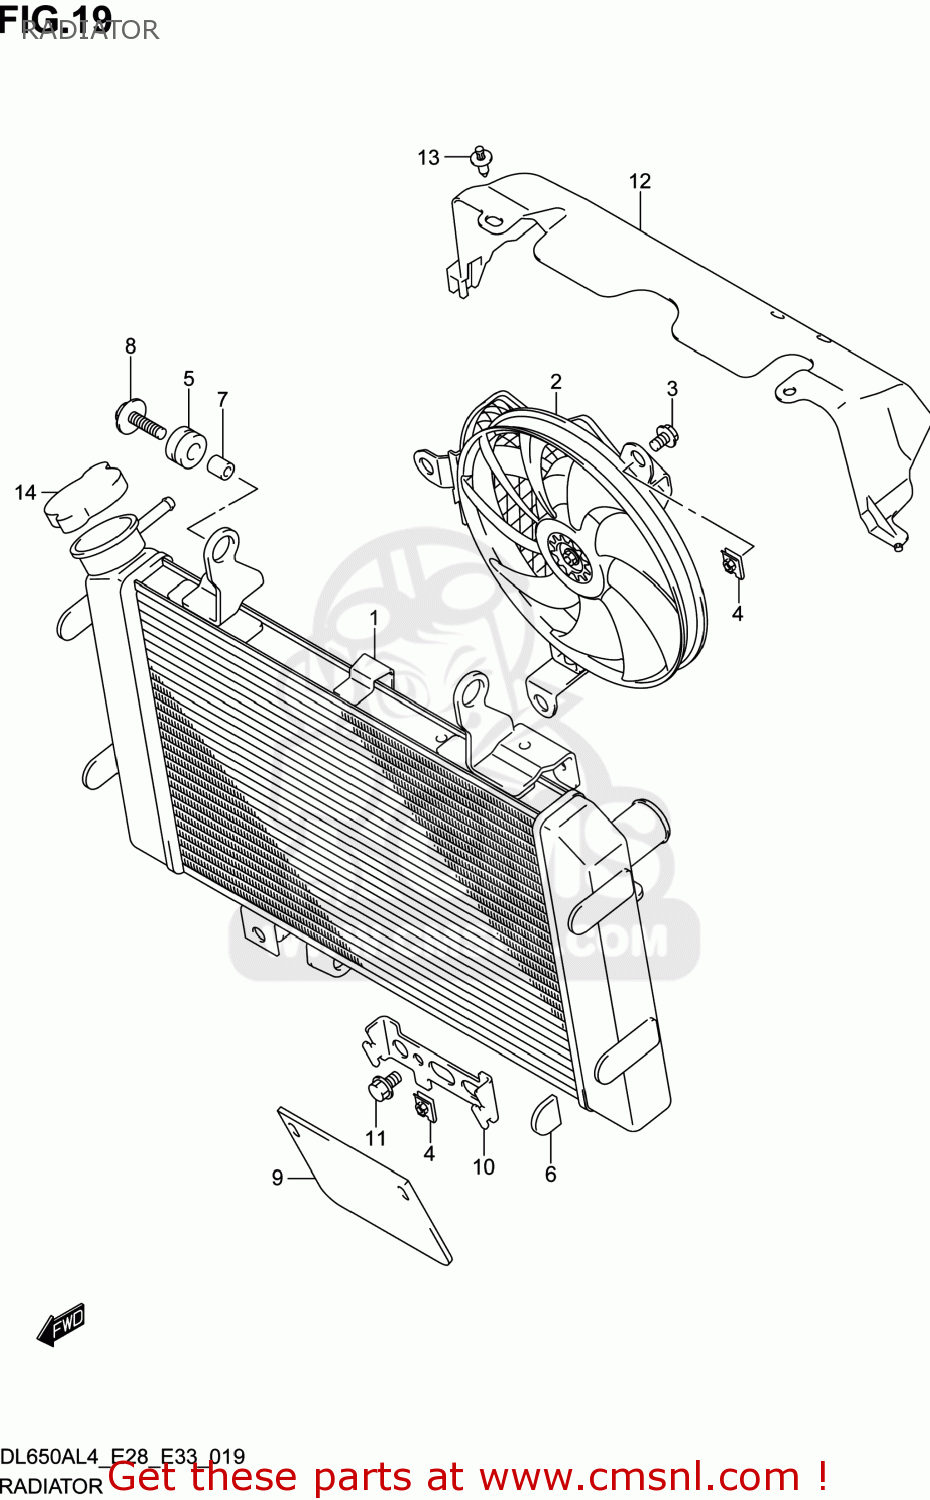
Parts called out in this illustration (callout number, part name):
1	RADIATOR ASSY,WATER
2	FAN ASSY,RADIATOR
3	BOLT,FAN ASSY
4	NUT,FAN ASSY
5	CUSHION
6	CUSHION
7	SPACER(6.5X10X10)
8	BOLT(6X25)
9	RUBBER,RADIATOR UNDER
10	BRACKET,RADIATOR UNDER RUBBER
11	BOLT
12	SHIELD,RADIATOR HEAT
13	CLIP(BLACK)
14	CAP,RADIATOR
